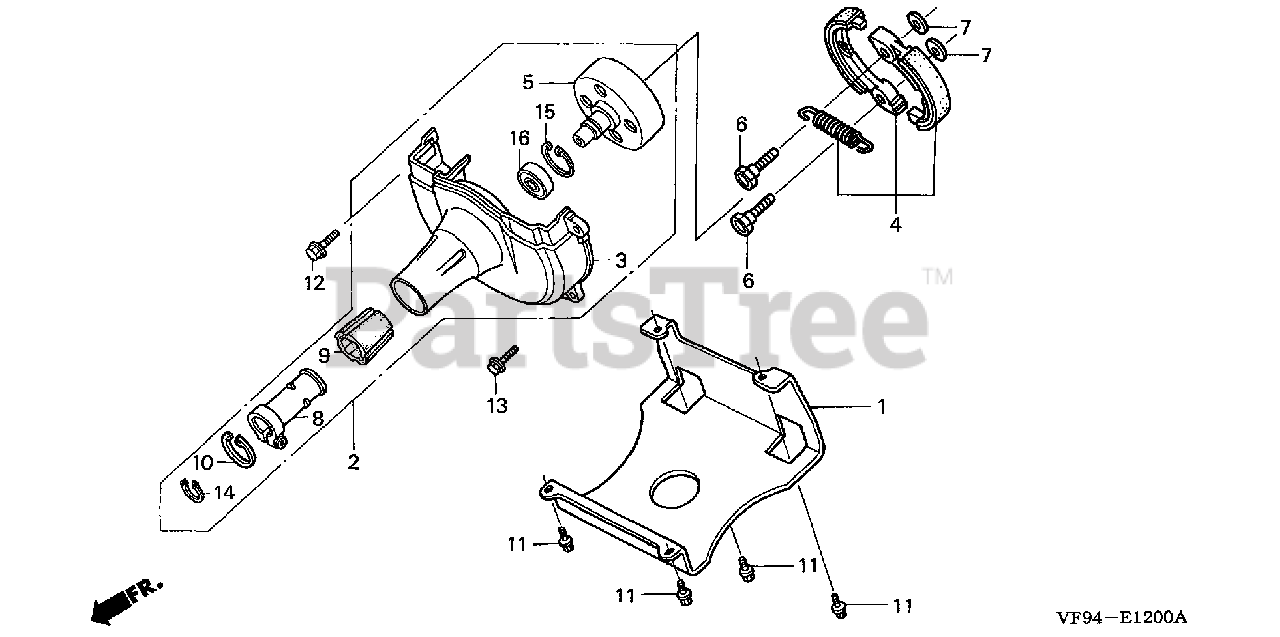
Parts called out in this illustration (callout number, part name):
1	GUARD, TANK
2	COVER ASSY., FAN *NH35M* (CLOUD SILVER METALLIC)
3	COVER, FAN *NH35M* (CLOUD SILVER METALLIC)
4	CLUTCH ASSY.
5	CLUTCH (OUTER)
6	BOLT, CLUTCH (8MM)
7	WASHER, CLUTCH (8X17)
8	BRACKET, ENGINE MOUNTING
9	RUBBER, ENGINE MOUNTING
10	CIRCLIP (INNER) (45MM)
11	BOLT, FLANGE (5X12)
12	BOLT, FLANGE (5X18)
13	BOLT, FLANGE (5X22)
14	CIRCLIP (OUTER) (15MM)
15	CIRCLIP (INNER) (35MM)
16	BEARING, RADIAL BALL (6202)
